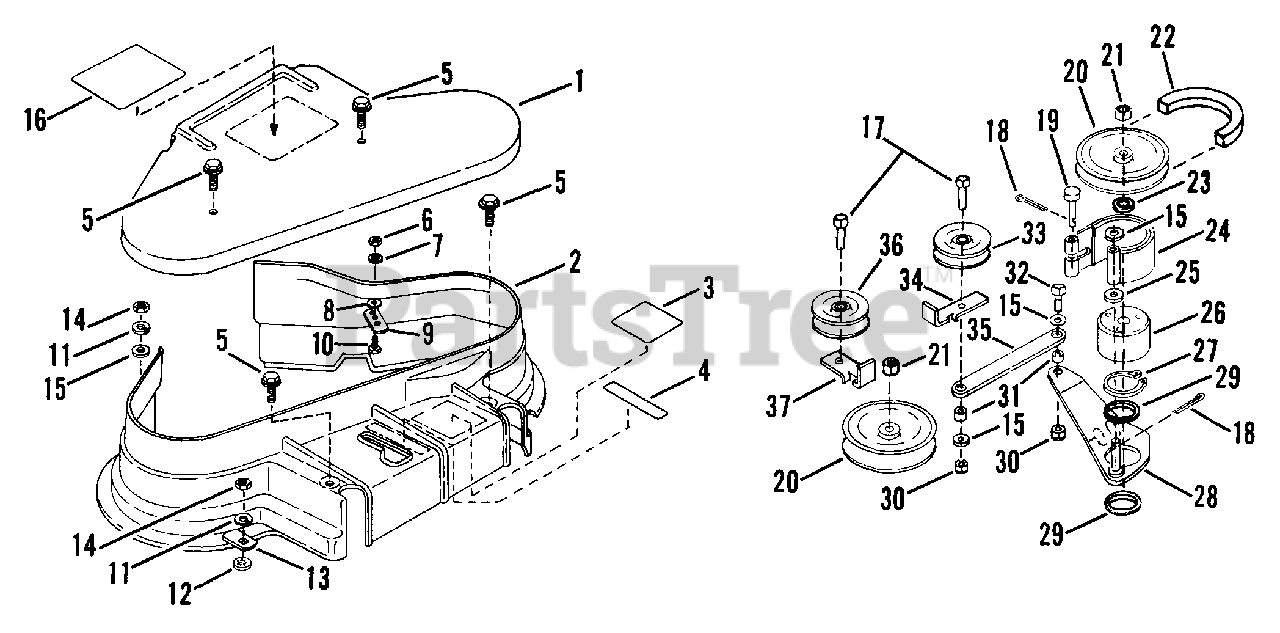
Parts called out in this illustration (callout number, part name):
1	ASSEMBLY, 41" Cover (Top)
2	ASSEMBLY, 41" Cover (Bottom)
3	DECAL, Brake Operation
4	DECAL, Blade, ON-OFF
5	SCREW, 1/4-28 x 5/8" Hex Head, Self-Tapping
6	NUT, 1/4-20 Hex
7	WASHER, 1/4 Internal Tooth Lock
8	WASHER, 1/4 Flat
9	GUIDE, Belt
10	SCREW, 1/4-20 x 1/2" Hex Head Cap
11	WASHER, 3/8 Split Lock
12	RETAINER, 3/8 Bolt
13	CLIP
14	NUT, 3/8-16 Hex
15	WASHER, 3/8" Flat
16	DECAL, Caution
17	SCREW, 3/8-24 x 1 3/4" Hex Head Cap
18	PIN, 3/32 x 3/4" Cotter
19	PIN, 1/4 Clevis
20	PULLEY, 5" O.D.
21	NUT, 3/4-16 Hex Jam Lock
22	BELT, AA105
23	WASHER, 3/4 Flat
24	BAND, Brake Assembly
25	SPACER
26	BRAKE DRUM
27	RING, 2" External Retaining
28	BRAKE ARM ASSEMBLY
29	WASHER, 2" I.D.
30	NUT, 3/8-24 Hex Lock
31	SPACER
32	SCREW, 3/8-24 x 3/4" Hex Head Cap
33	PULLEY, Idler
34	RESTRICTOR
36	PULLEY, Idler
37	GUIDE, Belt
